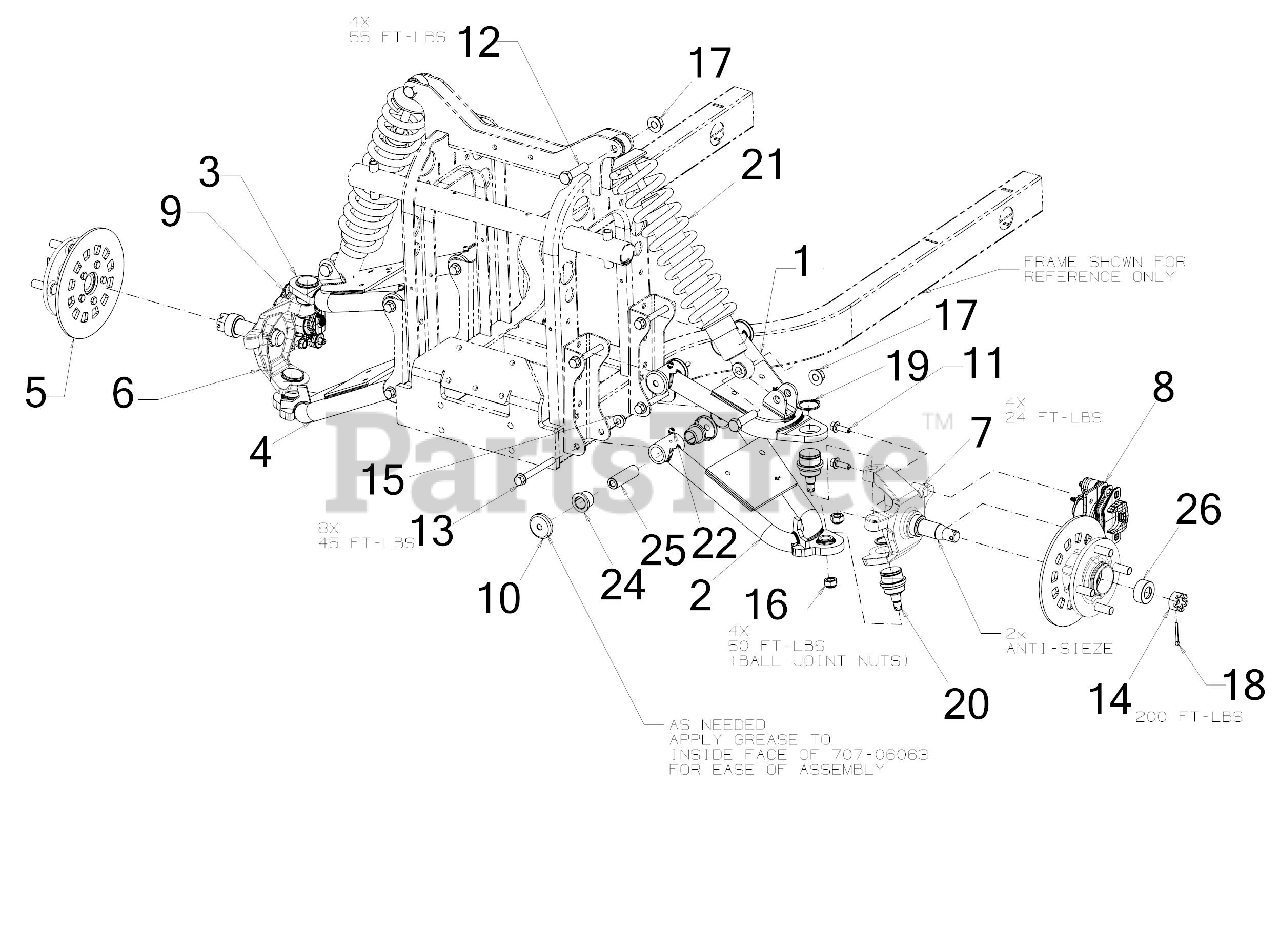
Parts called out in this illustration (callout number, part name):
1	UPPER CONTROL ARM TUBE ASSEMBLY (LH)
2	LOWER CONTROL ARM TUBE ASSEMBLY (LH)
3	UPPER CONTROL ARM TUBE ASSEMBLY (RH)
4	LOWER CONTROL ARM TUBE ASSEMBLY (RH)
5	WHEEL HUB ASSEMBLY
6	RIGHT FRONT KNUCKLE ASSEMBLY
7	LEFT FRONT KNUCKLE ASSEMBLY
8	FRONT BRAKE CALIPER ASSEMBLY (RH)
9	FRONT BRAKE CALIPER ASSEMBLY (LH)
10	PIVOT ARM BRACKET CAP
11	SCREW M8 x 1.25 x 25MM GR8.8
12	SCREW 1/2-13 x 2 GR5
13	HEX FLANGE BOLT 3/8-16:3.50
14	HEX NUT CASTLE 3/4-16
18	COTTER PIN-5/32 DIA
19	RETAINING RING
20	BALL JOINT
21	SHOCK ABSORBER
22	GREASE FITTING
24	FLANGE BEARING .75 X .993
25	SPACER .385 X .75 X 1.873
26	SPACER .77 X 1.45 X .630
